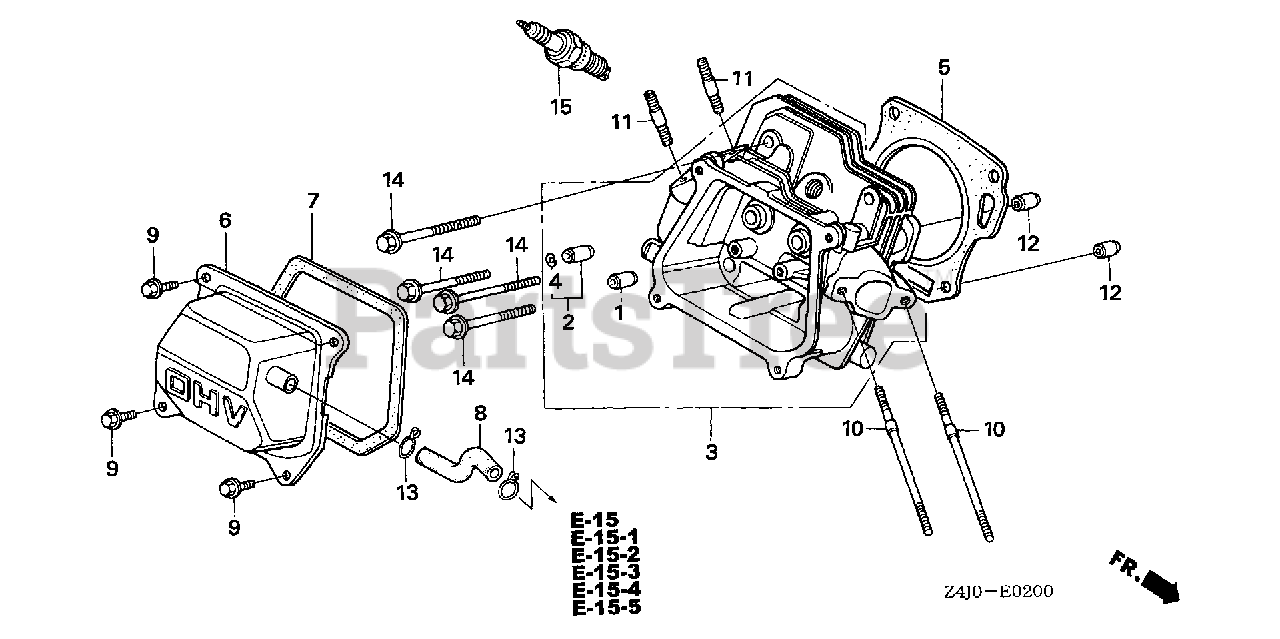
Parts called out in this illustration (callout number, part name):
1	GUIDE, VALVE (OVER SIZE) Use from Engine SN 6324986.
2	GUIDE, EX. VALVE (OS)
3	CYLINDER HEAD
4	CLIP, VALVE GUIDE Use from Engine SN 1231803.
5	GASKET, CYLINDER HEAD
6	COVER, HEAD
7	GASKET, CYLINDER HEAD COVER
8	TUBE, BREATHER
9	BOLT, FLANGE (6X12) (CT200)
10	BOLT, STUD (6X109)
11	BOLT, STUD (8X32)
12	PIN A, DOWEL (10X16)
14	BOLT, FLANGE (8X60)
15	SPARK PLUG (BPR5ES) (NGK)
15	SPARK PLUG (W16EPR-U) (DENSO)
15	SPARK PLUG (BPR6ES) (NGK)
15	SPARK PLUG (W20EPR-U) (DENSO)
